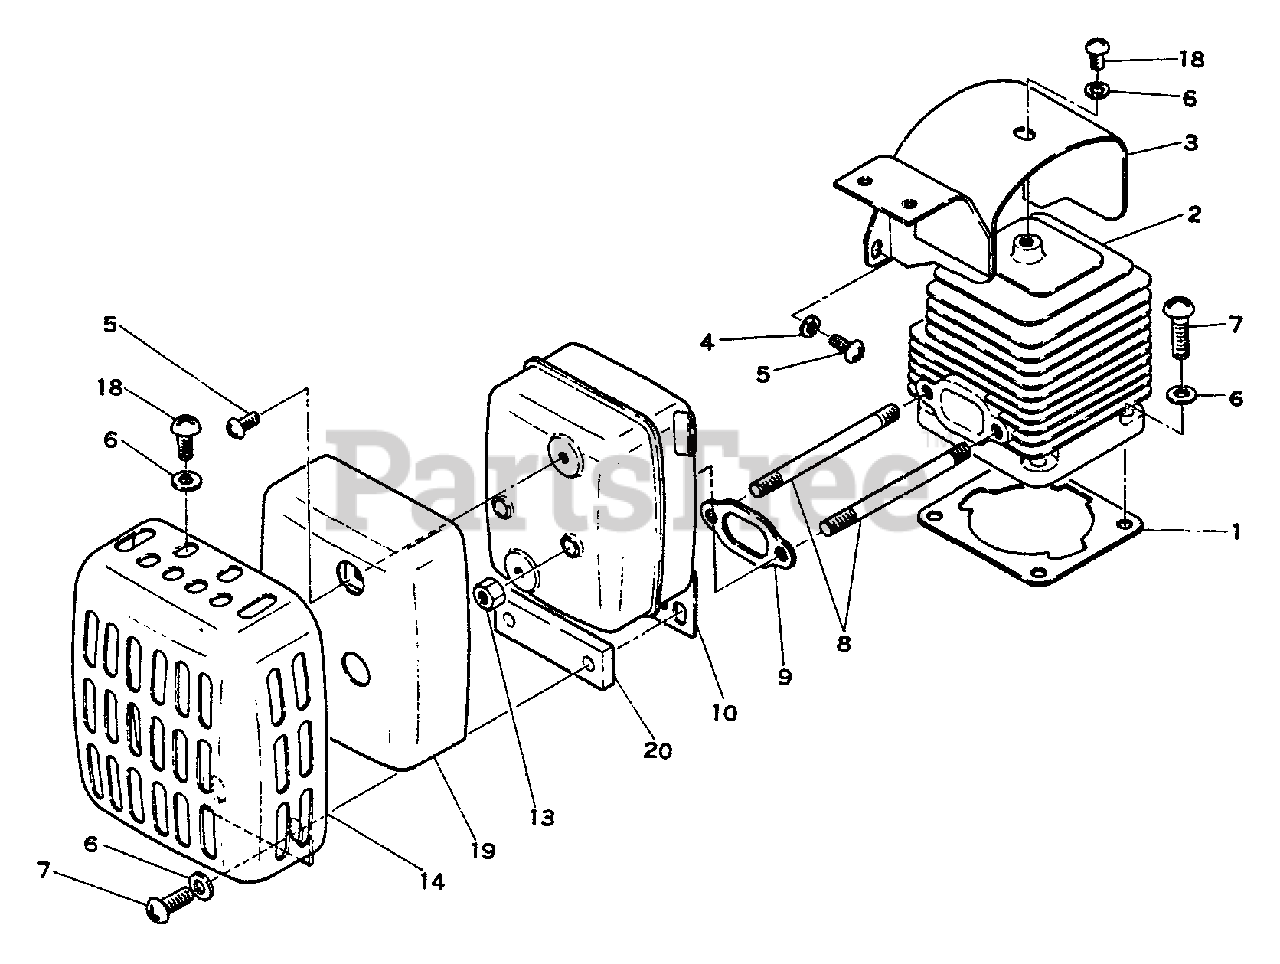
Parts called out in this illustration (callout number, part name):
1	GASKET, CYLINDER
2	CYLINDER
3	SHIELD, CYLINDER
4	WASHER 4 MM
5	SCREW 4×8
6	WASHER, FLAT 5.5×10×0.8
7	SCREW 5×16
8	STUD
9	GASKET, MUFFLER
10	MUFFLER
13	LOCKNUT - 5
14	COVER, MUFFLER
18	SCREW 5×10
19	INSULATOR
20	SPACER
